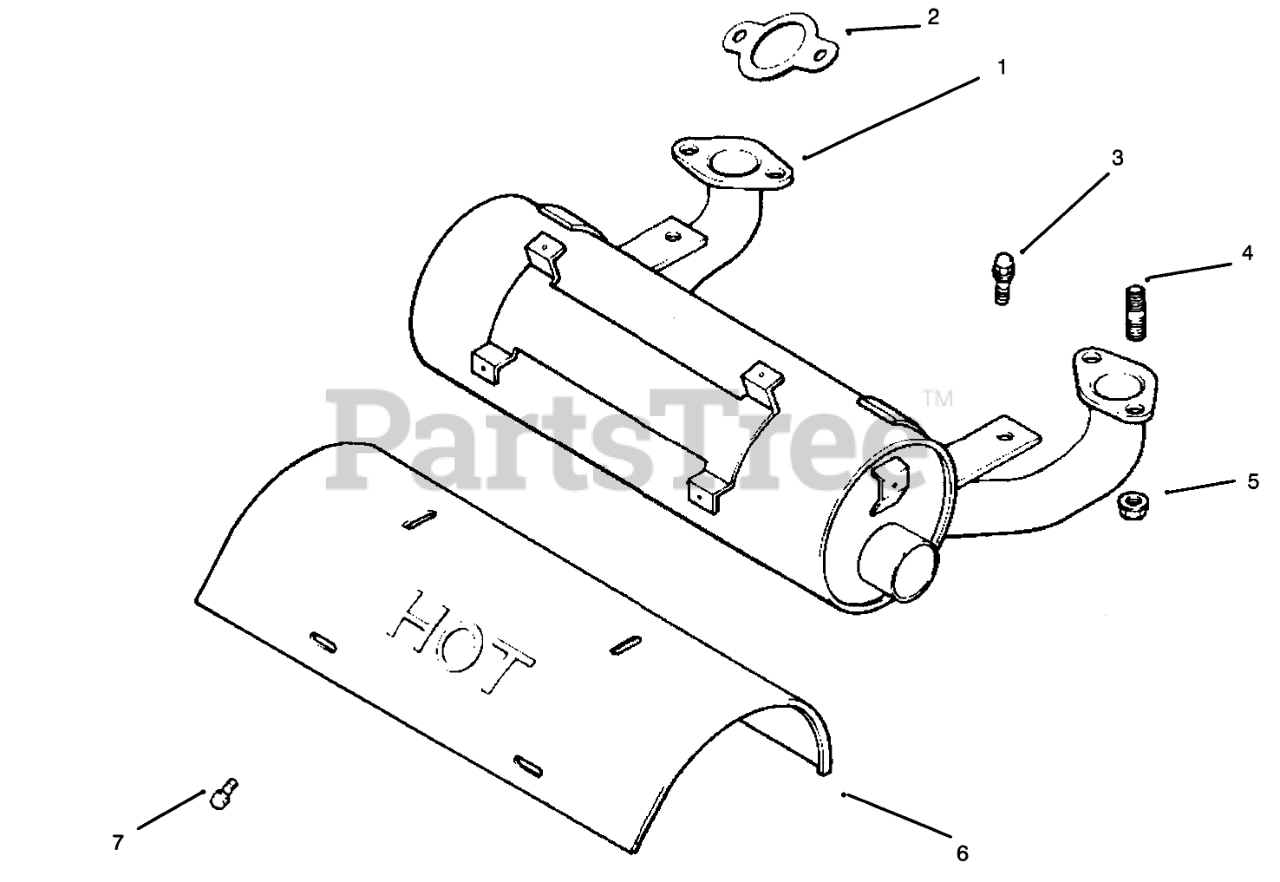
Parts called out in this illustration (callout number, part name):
1	Muffler
2	Gasket-Exhaust
3	Screw
4	Stud
5	Nut
6	Duct-Heat Shield
7	Screw
